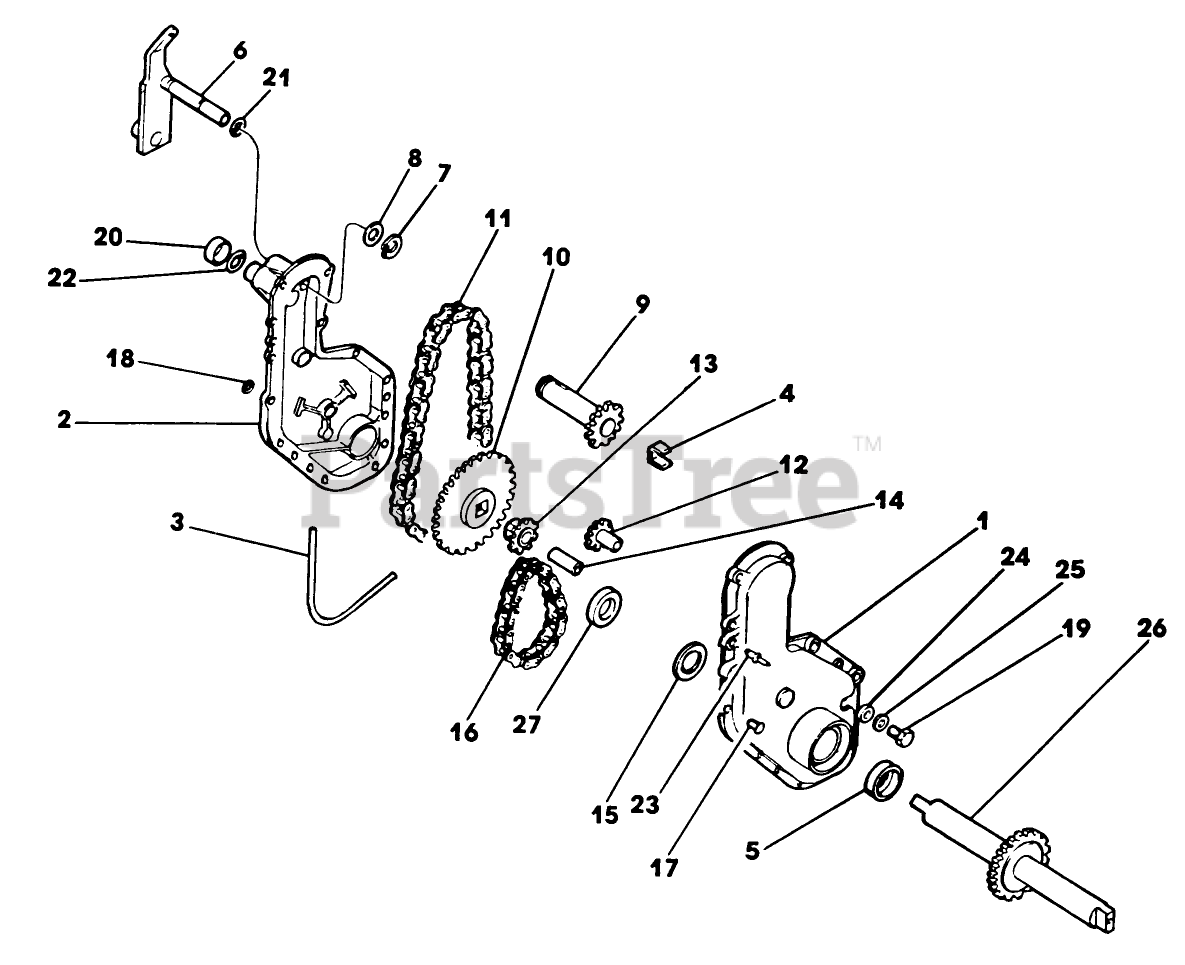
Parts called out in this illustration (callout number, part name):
6	IDLER ARM ASSEMBLY
10	SPROCKET
12	IDLER-SPROCKET
13	SPROCKET
